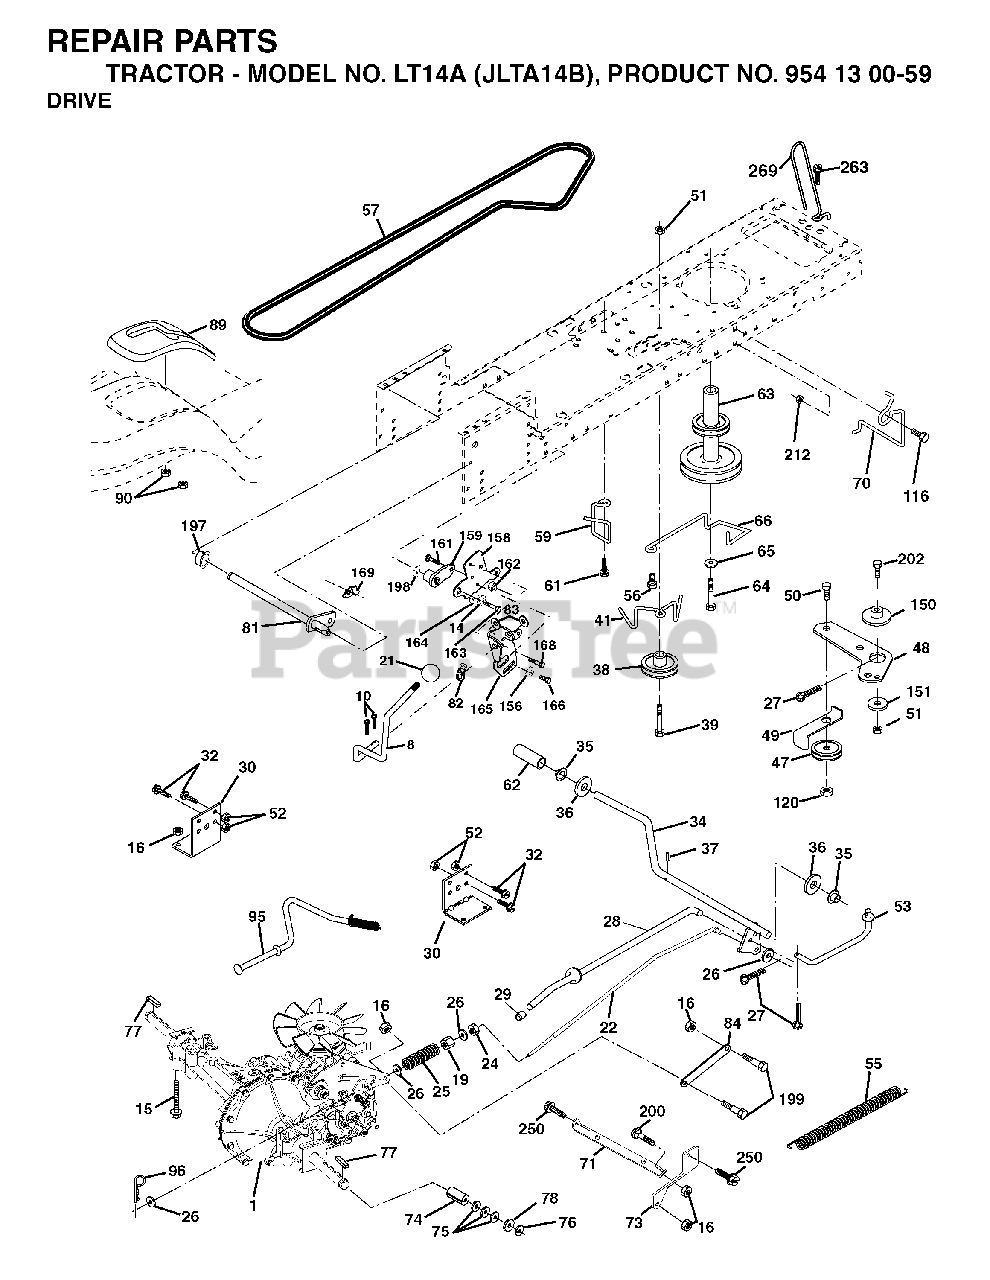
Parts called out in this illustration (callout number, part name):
8	ROD SHIFT FENDER ADJUST STLT
10	PIN COTTER
14	LOCKWASHER
15	BOLT HEX 5/16-18 GR 5
16	NUT.71038.31-18.HEX.NYLOCK
19	NUT
21	KNOB.DUCKHEAD.1/2
22	ROD BRAKE HYDRO
24	NUT
25	SPRING ROD LT
27	COTTER PIN
28	ROD, PARKING BRAKE
29	PLUNGER CAP
30	BRKT, MOUNT TRNSAXLE
32	BOLT
34	SHAFT, FOOT PEDAL
35	BEARING.NYLON
36	WASHER LT
37	DRIVE PIN
38	PULLEY IDLER COMPOSITE
39	BOLT
41	KEEPER, BELT IDLER
47	IDLER PULLEY
48	BELLCRANK, CLUTCH
49	RETAIN BELT
50	BOLT.3/8-16X1.50
51	LOCKNUT
52	LOCKNUT
53	LINK, CLUTCH LT
55	SPRING, RETURN LT
56	SCREW 3/8-16X.875
57	DRIVE BELT, LTH & YTH TRACTORS
59	KEEPER, BELT CENTER
61	SCREW 3/8-16X.875
62	PEDAL COVER T
64	BOLT
65	LOCKWASHER
66	KEEPER BELT ENGINE
71	STRAP TORQUE LH HYDRO
73	STRAP TORQUE RH HYDRO
74	SPACER AXLE
76	E-RING LT
77	SQUARE KEY
81	SHAFT ASM CROSS TAPERED
82	SHIFT SPRING
83	WASHER
95	CONTROL ASM. BYPASS HYDRO
96	RETAINER M
103	NUT.HEX.1/2-20
116	BOLT D
120	NUT LOCK FLG 3/8-16 UNC
150	SPACER, RETAINER
151	WASHER 12/32X2X10GA
156	WASHER.SRRTD.5/16
158	BRACKET
159	HUB
161	BOLT
162	NUT.CROWNLOCK.1/4
163	BOLT
165	RP BRACKET
168	BOLT.SHOULDER.5/16-18X
169	PLATE.FASTENING.CROSS.SHAFT
197	NYLINER SNAP 5/8" ID
198	WASHER.NYL.7/8IDX.105"HYD CR
199	BOLT SHOULDER 5/16-18 UNC
200	BOLT
202	BOLT
205	WASHER
212	NUT
250	SCREW 3/8-16X3/4
263	SCREW, 3/8-16X3/4
